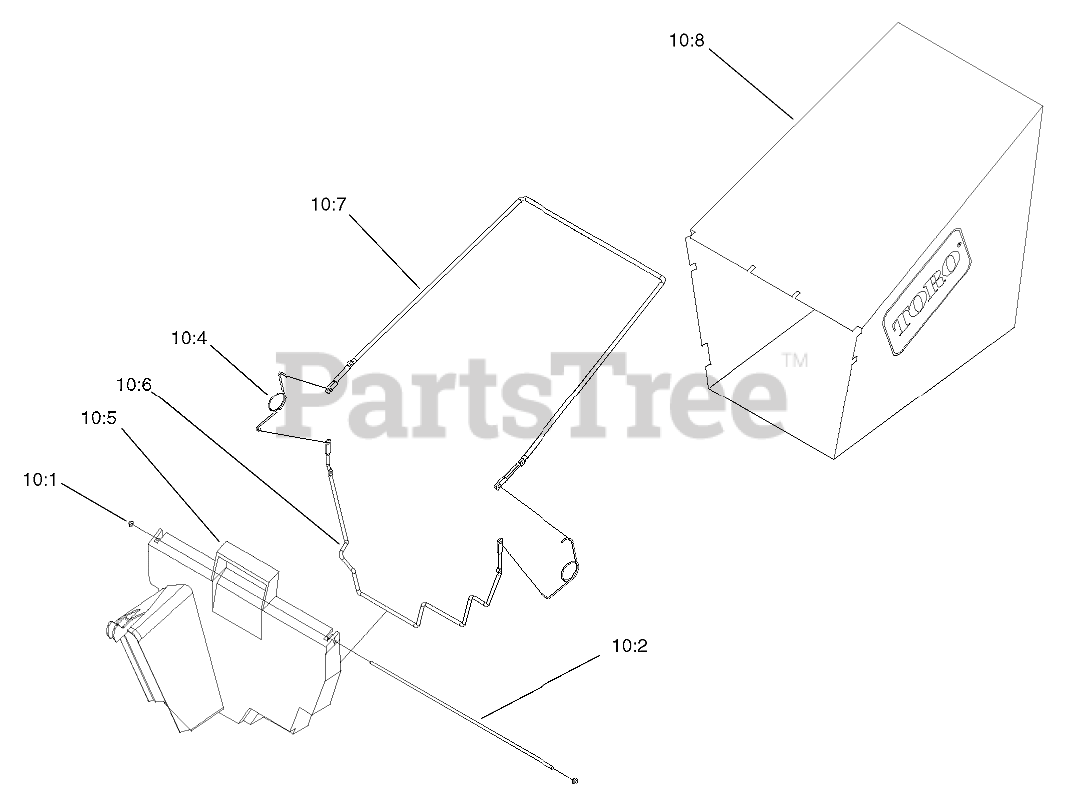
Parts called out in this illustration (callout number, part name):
10	GRASS BAG ASM
10:1	NUT-PUSH
10:2	HINGE-DOOR, BAG
10:4	SPRING
10:5	DOOR-BAG
10:6	FRAME-BAG
10:7	FRAME-BAG, UPPER
10:8	BAG-GRASS
